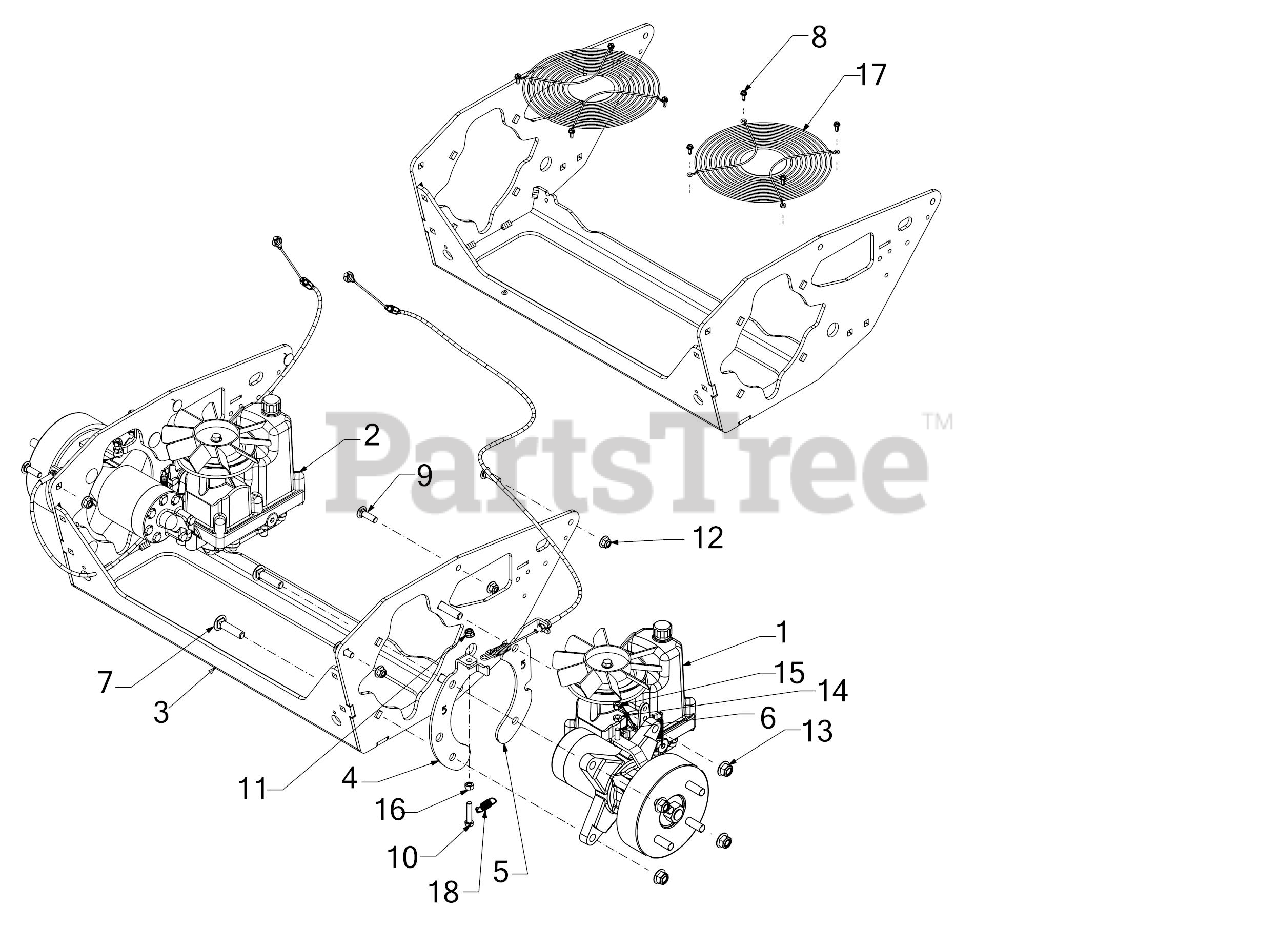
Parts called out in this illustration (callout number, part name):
1	TRANSMISSION / MOTOR ASSEMBLY (RH)
2	TRANSMISSION / MOTOR ASSEMBLY (LH)
3	TRANSMISSION MOUNTING BRACKET
4	SPRING BRAKE MOUNTING BRACKET
5	BRAKE CABLE BRACKET
6	SCREW 5/16-18 x 1.0 GR5
7	CARRIAGE BOLT 1/2-13 GR5
8	SCREW 10-24 x 0.500
9	CARRIAGE BOLT 3/8-16 X1.25 GR5
10	SCREW 5/16-18 x 1.5 LG
11	FLANGE LOCK NUT 5/16-18
15	HEX NUT
16	HEX NUT
18	EXTENSION SPRING .500 OD x 1.71
